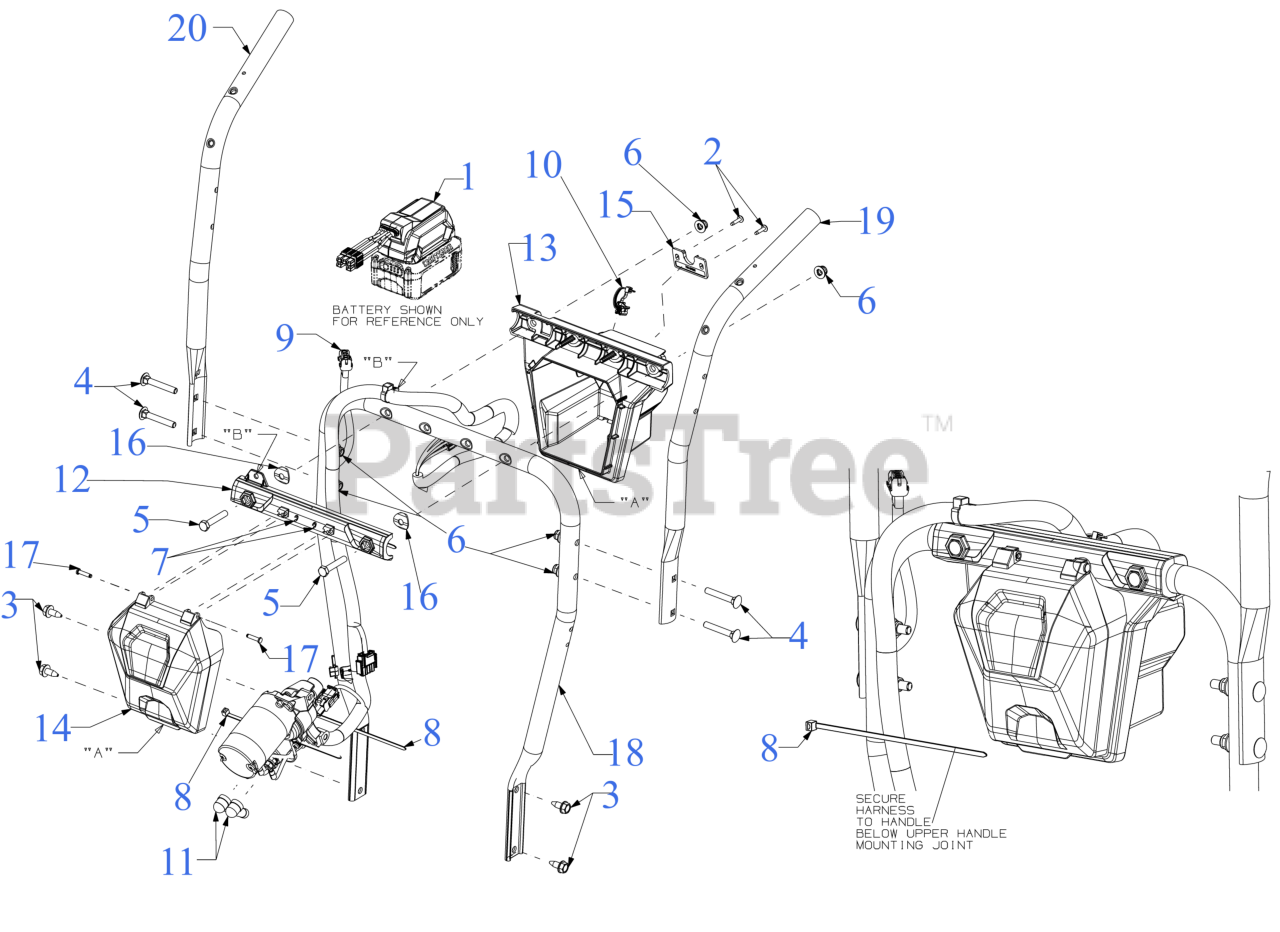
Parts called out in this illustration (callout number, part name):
1	BATTERY ADAPTER
2	SCREW 8-16 x 3/4
3	SCREW 5/16-18 x .750
4	CARRIAGE BOLT 5/16-18 x 2.00 GR5
5	SCREW 5/16-18 x 1.75 GR5
6	FLANGE LOCK NUT 5/16-18
7	E-RING
8	7" CABLE TIE
9	HARNESS (2S/ESTRT/LED)
10	EDGE MOUNT ZIP TIE CLIP
11	COVER BOOT
12	BATTERY HOUSING COVER
13	BATTERY HOUSING
14	BATTERY DOOR HOUSING
15	BATTERY BOX CLAMP
16	SADDLE WASHER
17	STEERING TRIGGER PIN 3/16
18	LOWER HANDLE
19	UPPER HANDLE (LH)
20	UPPER HANDLE (RH)
